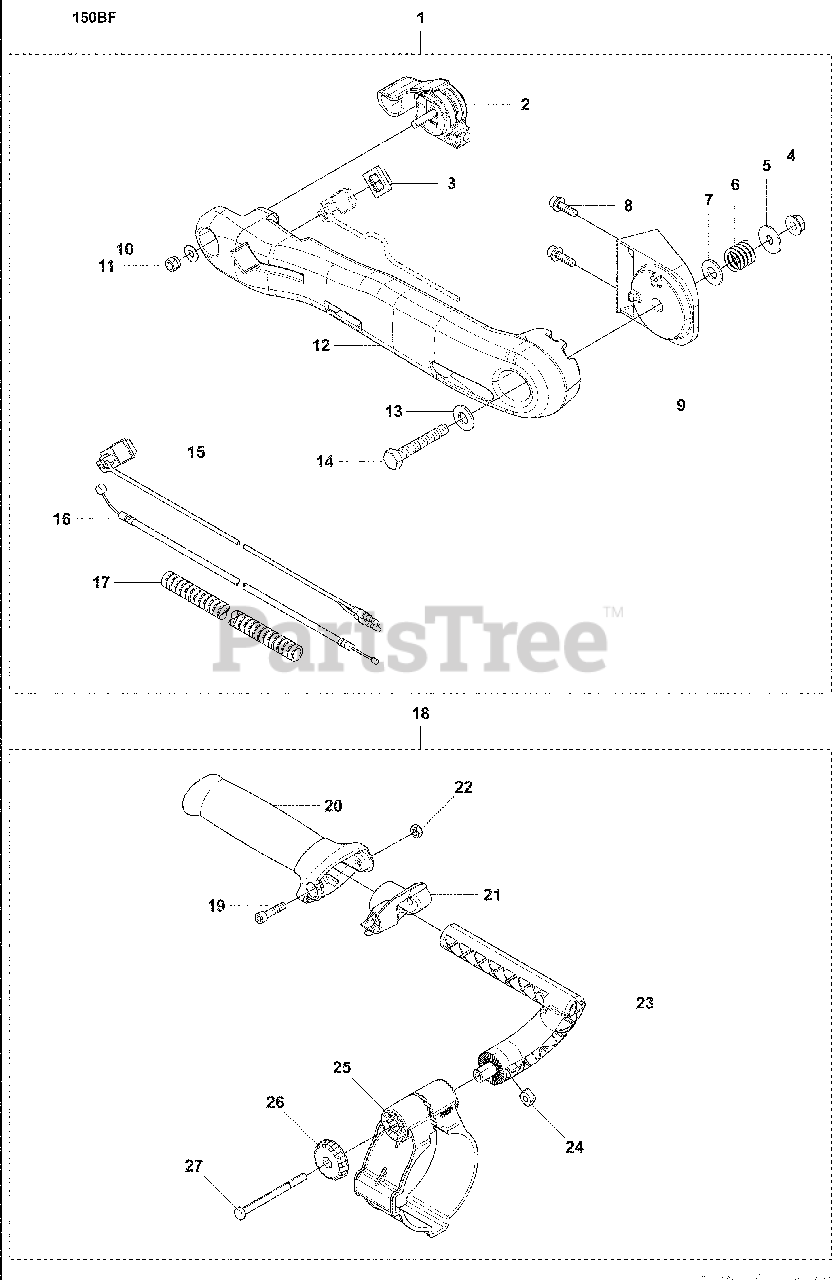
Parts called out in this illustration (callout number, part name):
1	Handle Assembly
2	Lever
3	Switch Cap
4	Nut
5	Washer
6	Spring
7	Washer
8	Screw
9	Bracket
11	Nut
12	ARM
13	Washer
14	Bolt
15	Kill Switch
16	Cable, Complete
18	Grip Assembly
19	Screw
22	Hex Nut, M5 X .80 DIN
23	Holder
24	Square Nut
25	Holder, TH
26	Air Filter Cover Knob
